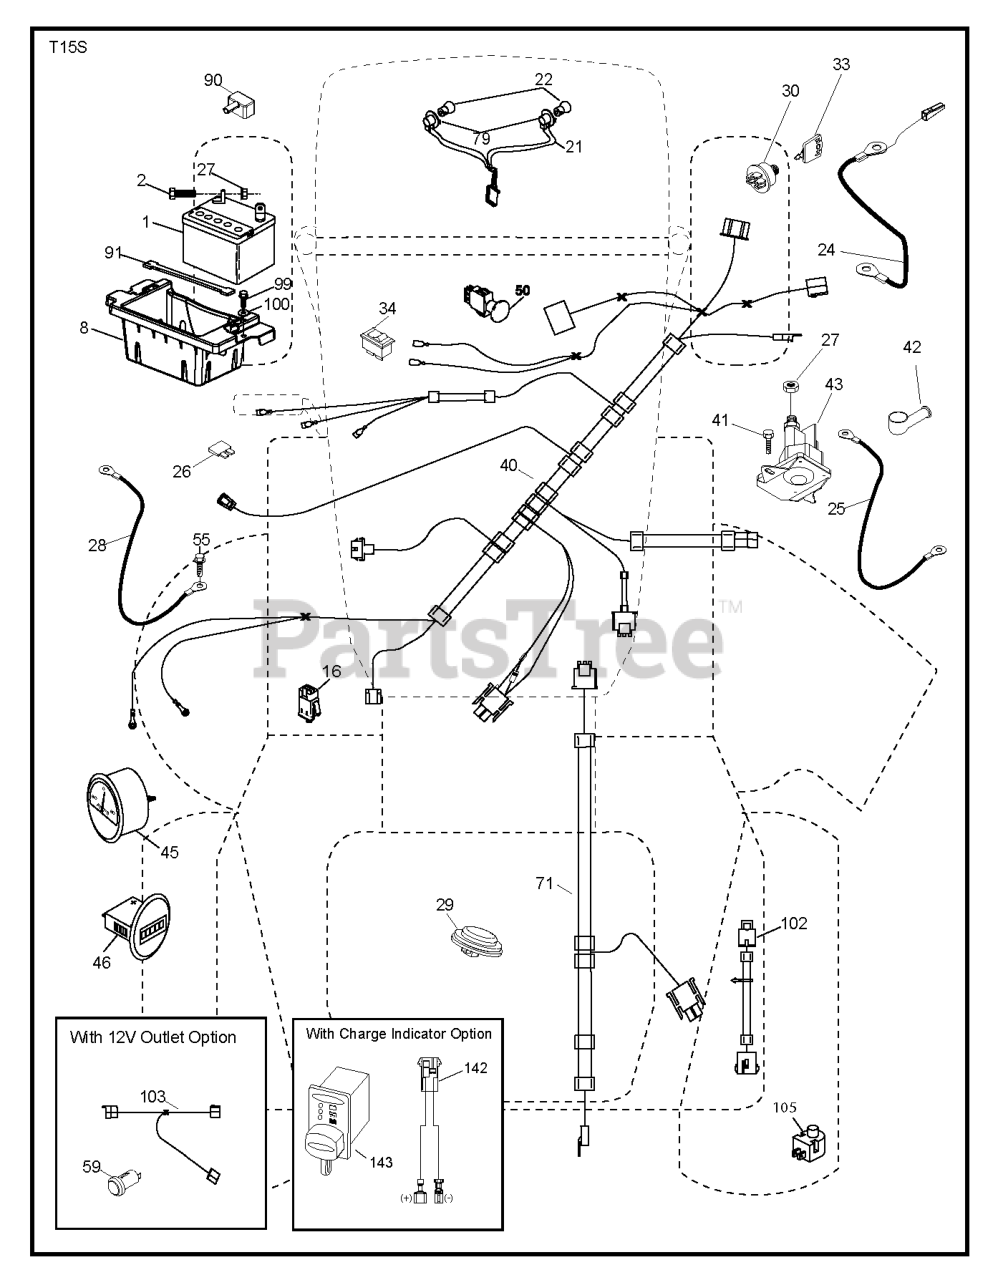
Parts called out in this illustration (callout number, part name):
1	Battery, Dry 30 Amp
2	BOLT.HEX.1/4.X.3/4.DICHROMATE
8	TRAY.ASM.BATTERY.FRT.TEX.CARB
16	SWITCH INTERLOOK PUSH-IN
21	HARNESS.LIGHT W/4152J BULBS
24	CABLE.BATT.POS.WIRE.TG.DA SOL
25	CABLE.STARTER.6G.BL/RED.17.5
26	FUSE 20AMP
27	NUT
28	CABLE GROUND 6 GA 21" 90T BLK
29	SWITCH.SEAT.DELTA.OPC.
30	SWITCH.IGN.DELTA.W.LGH.ROS
33	KEY.CHAIN.BLISTER.PACK.GEN.USA
40	HARNESS.IGN.DASH.W/112V.PORT
41	SCREW
42	TERMINAL COVER
43	SOLENOID.W/BRASS.PLUNGER
45	AMMETER GAUGE ROUND SNAP-IN
46	HOURMETER.GAUGE.RNK.SNAP.LS
50	RP.PTO.SWITCH.8 TERMINAL.BLACK
55	SCREW 5/16"
59	OUTLET.12-VOLT
71	HARNESS-CHASSIS SUB
79	BULB HOLDER ASM.
90	COVER.TERMINAL.BATTERY
91	STRAP.BATTERY.MOUNT.FRONT(2 2)
99	SCREW HEXWSHR 1/4-20X3/4
100	WASHER
102	HARNESS PIGTAIL PCH TEX ROS
103	HARNESS.PIGTAIL.12V.OUTLET.
105	REVERSE SWITCH
142	CHARGE.PORT.PIGTAIL HARNESS
143	CHARGE.PORT
